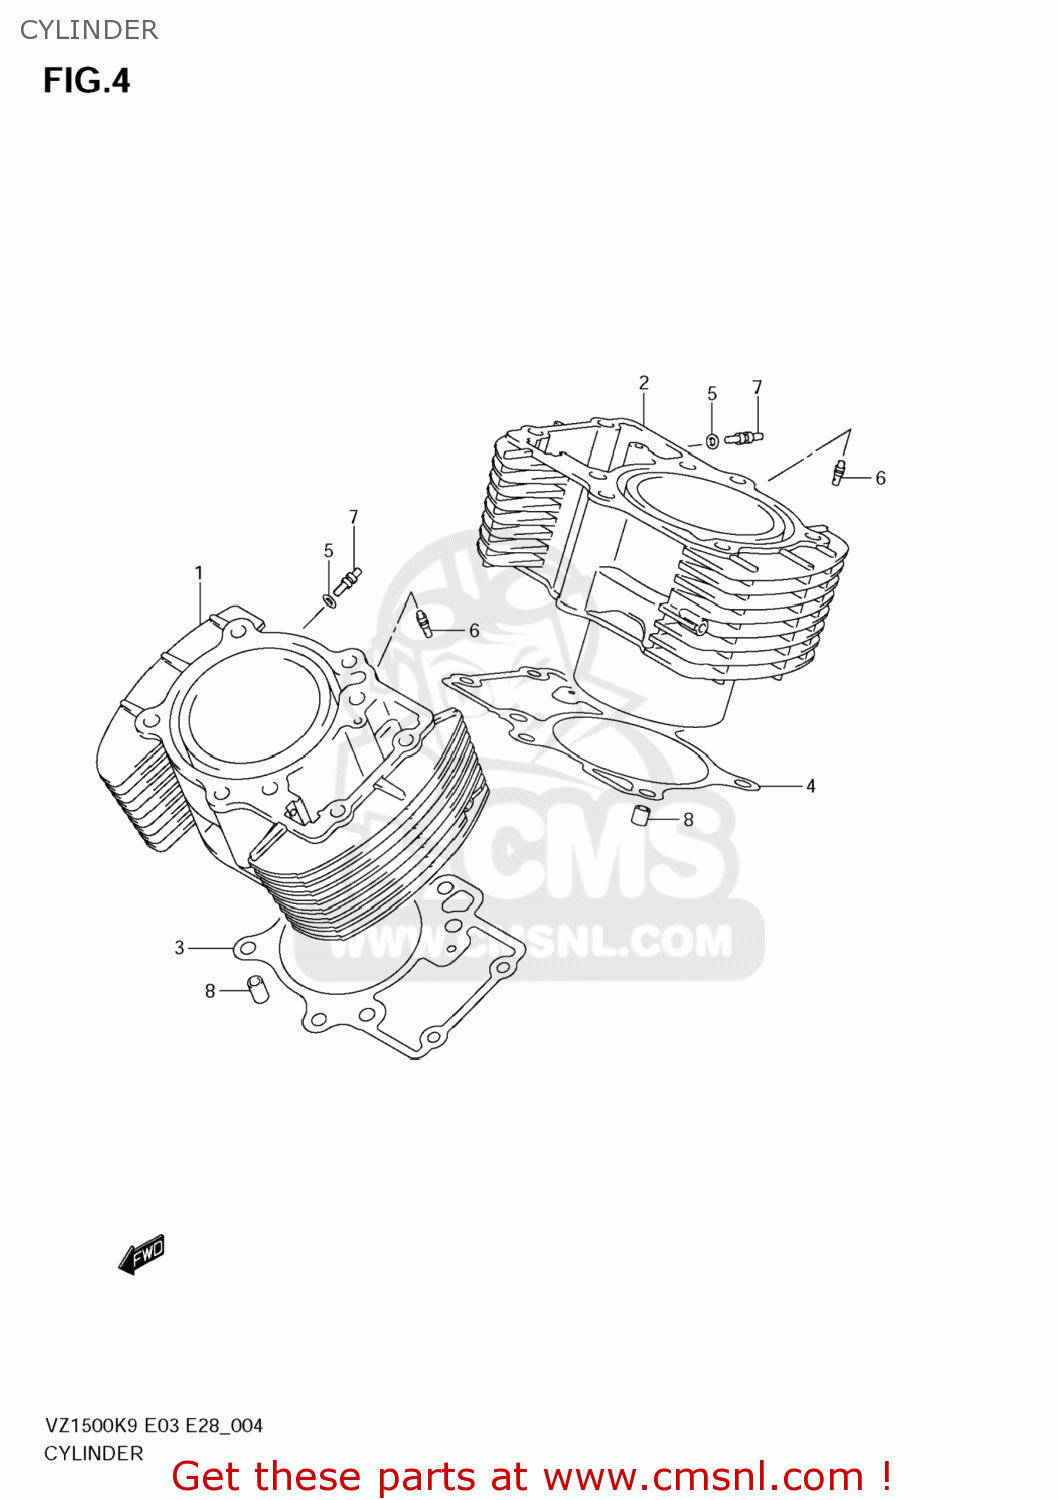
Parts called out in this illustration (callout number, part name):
1	CYLINDER,FR
2	CYLINDER,RR
3	GASKET,CYLINDER FR (NAS)
4	GASKET,CYLINDER RR (NAS)
5	O RING(D:1.2,ID:4)
6	JET,OIL GALLERY
7	JET(8)
8	PIN
